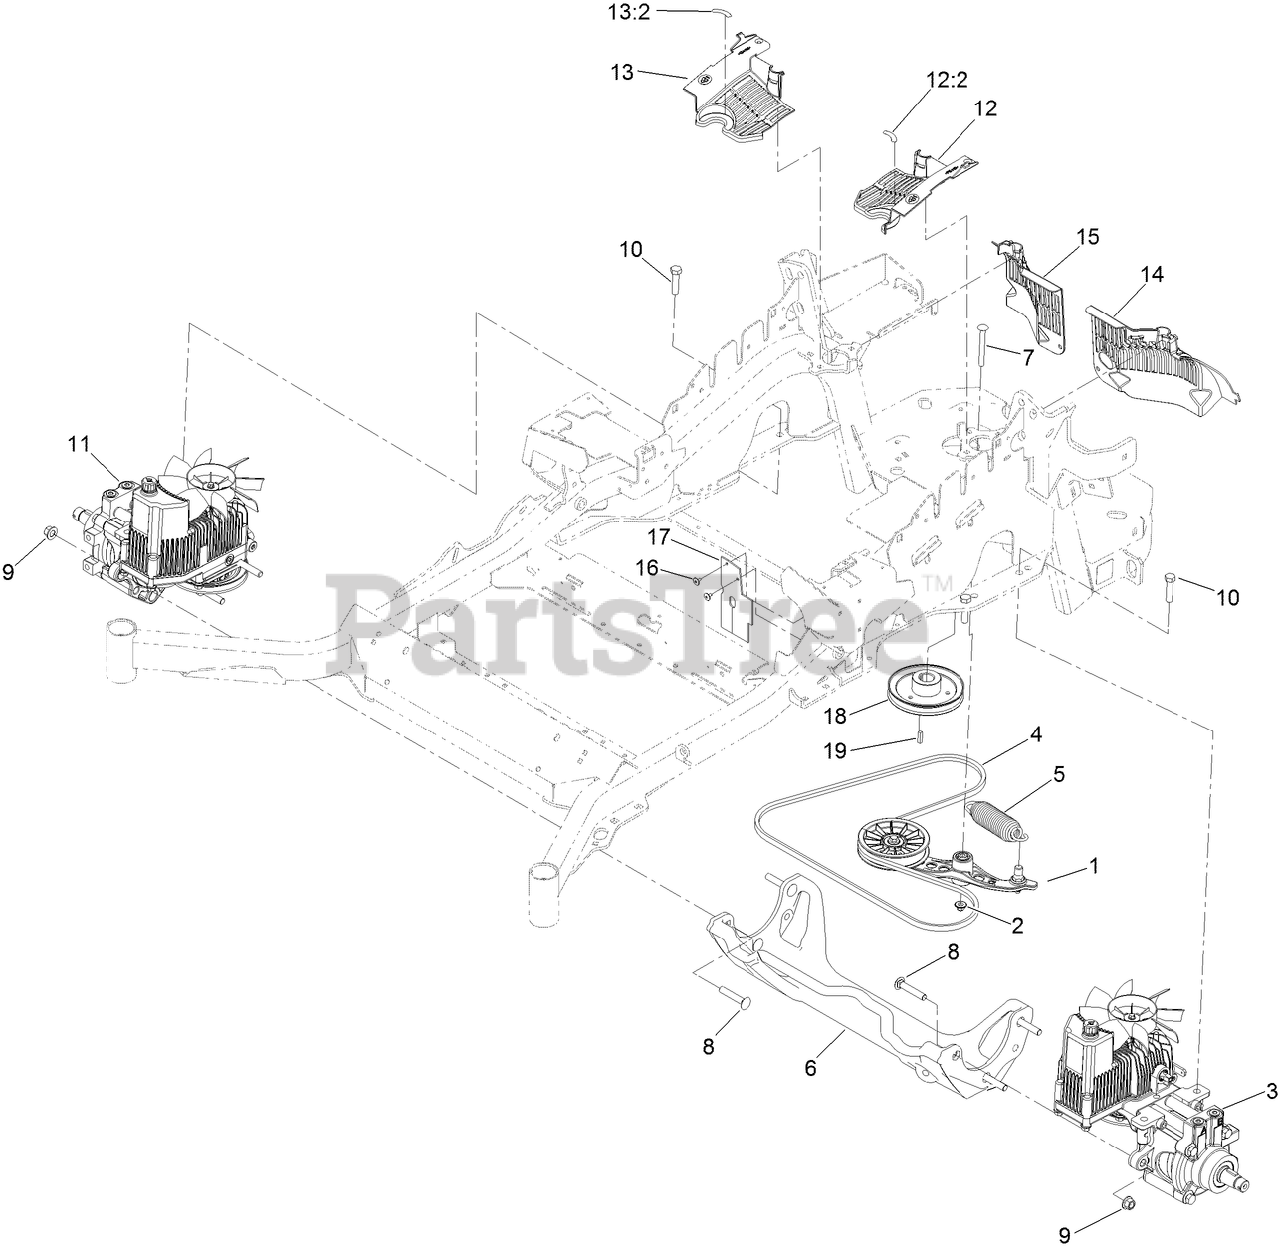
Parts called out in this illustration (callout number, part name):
1	PUMP IDLER ASM
2	NUT-FLANGE, NI
3	LH HYDRO ASM (16CC W/ SHOCK)
4	BELT
5	SPRING-EXTENSION
6	CRADLE-HYDRO
7	BOLT-SHOULDER, CARRIAGE
8	SCREW-CARR
9	NUT-LOCK
10	SCREW-HH
11	RH HYDRO ASM (16CC W/ SHOCK)
12	LH HYDRO GUARD ASM
12:2	DECAL-OIL, HYDRO
13	RH HYDRO GUARD ASM
13:2	DECAL-OIL, HYDRO
14	GUARD-HYDRO, REAR (LH)
15	GUARD-HYDRO, REAR (RH)
16	RIVET-POP
17	DEFLECTOR-AIR FLOW
18	SHEAVE
